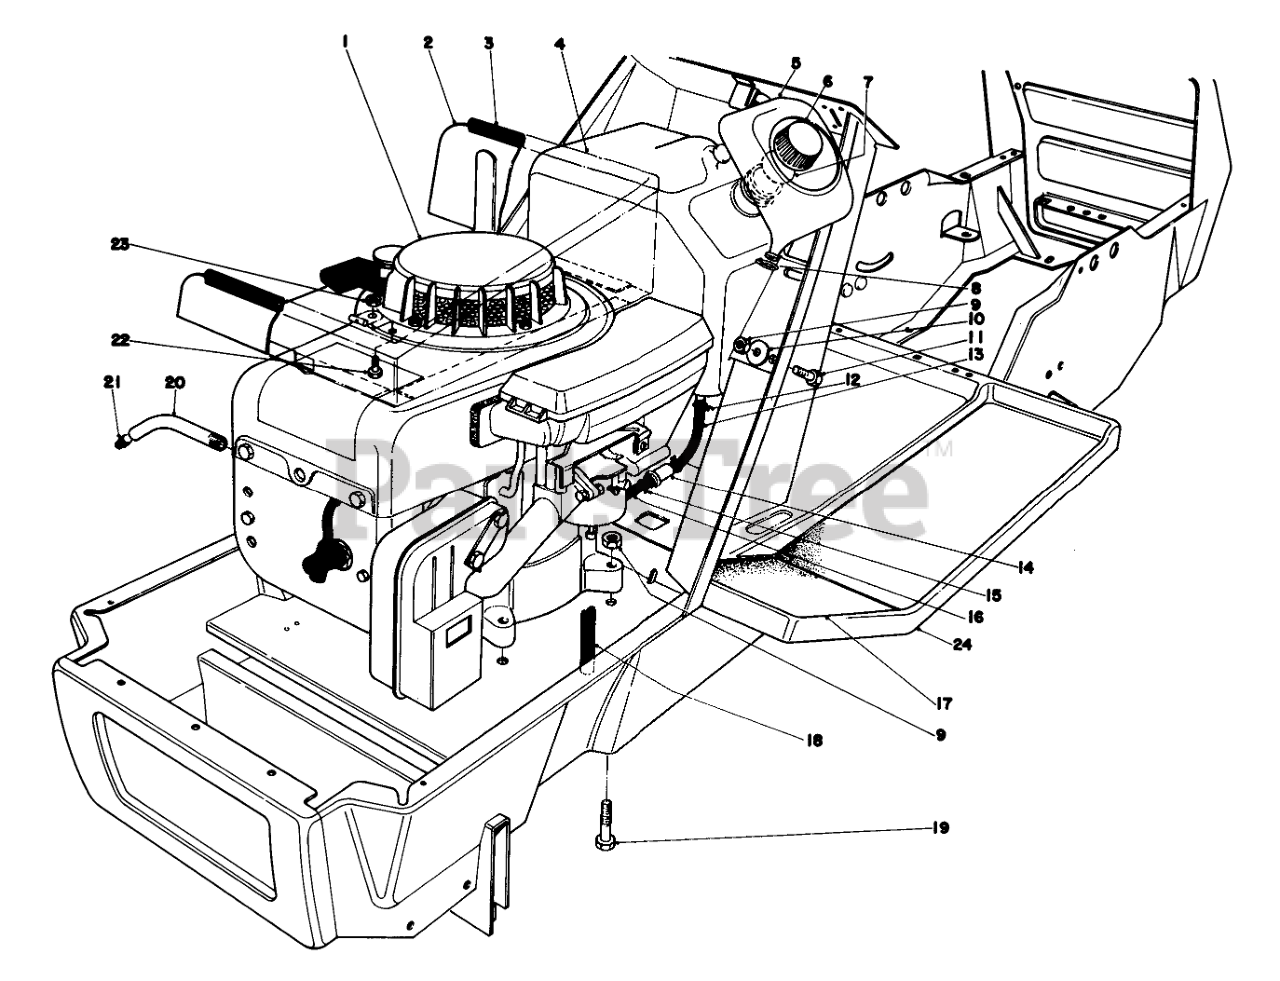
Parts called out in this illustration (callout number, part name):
1	Engine
2	AIR DUCT WA
3	Seal-Hood
4	Gas Tank (Incl. Ref. #5)
5	Funnel Overflow
6	Gas Cap (Incl. Ref. #7)
7	Gasket Gas Cap
8	HOSE CLAMP
9	NUT-LOCK, CONE
10	WASHER
11	SCREW-HH
12	CLAMP-HOSE
13	Hose-Gas
14	Fuel Filter
15	Clamp
16	Hose Gas
17	LH FOOT TREAD
18	Hose Funnel
19	SCREW-HH
20	OIL DRAIN TUBE
21	PLUG-PIPE, SQH
22	SCREW-HH
23	NUT-LOCK, CONE
24	Frame
